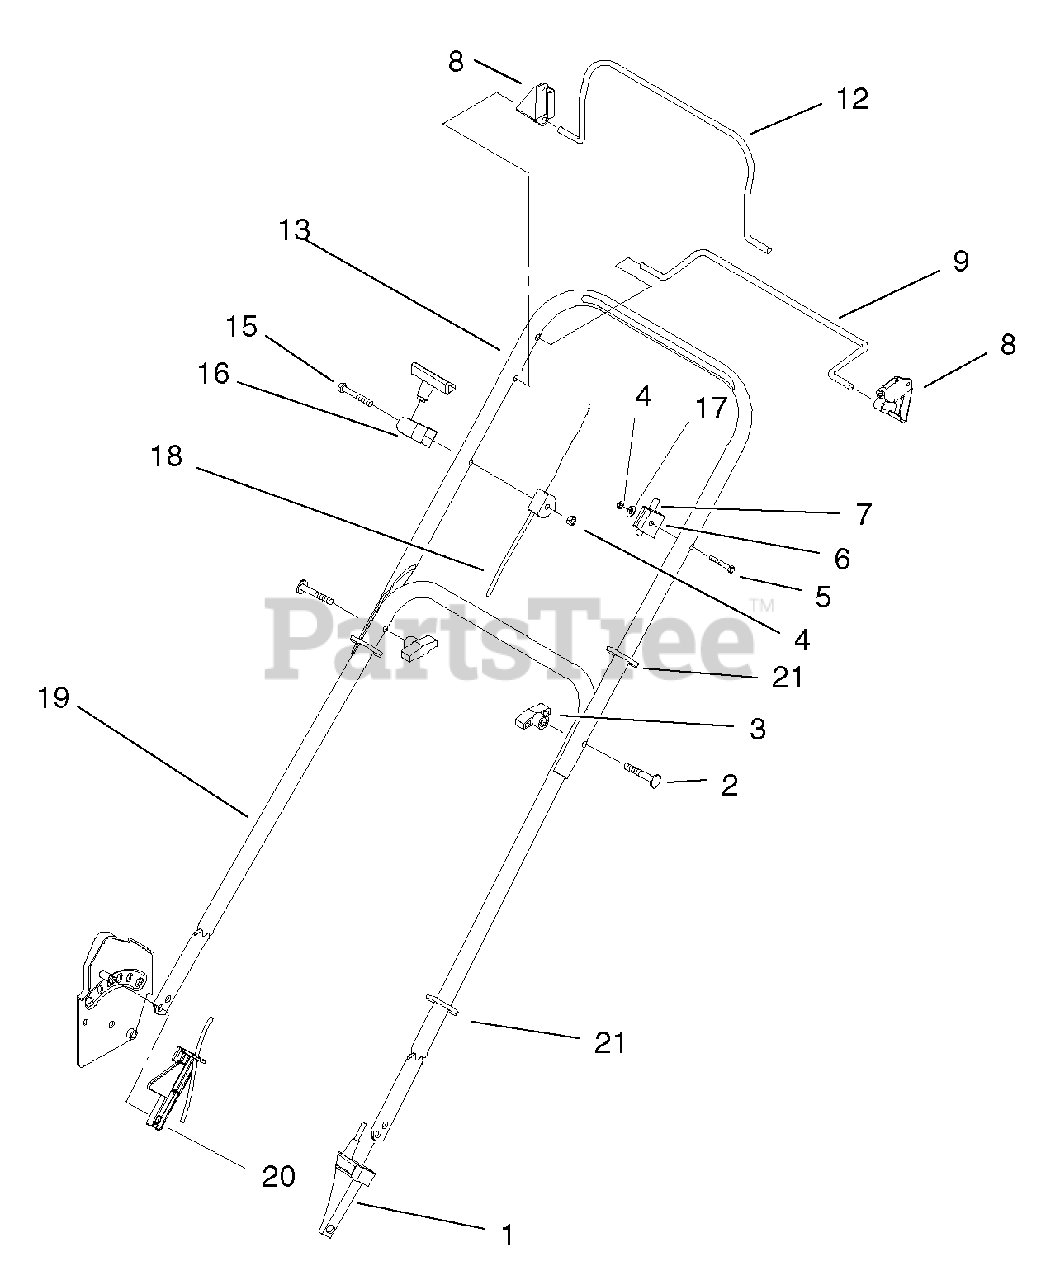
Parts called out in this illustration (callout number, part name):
1	Anchor-Cable
3	Knob-Handle
4	Nut-Lock, NI
5	Screw-Handle
6	Anchor-Upper, Cable
7	Cable-Ground Speed
8	Stop-Pivot
9	Bail-Control
12	Bail-Brake
13	Handle-Upper
15	Screw-HH
16	Rope-Guide
17	Washer-Flat
18	Brake Cable ASM
19	Handle-Lower Section
20	Guard-Handle
21	Tie Strap
